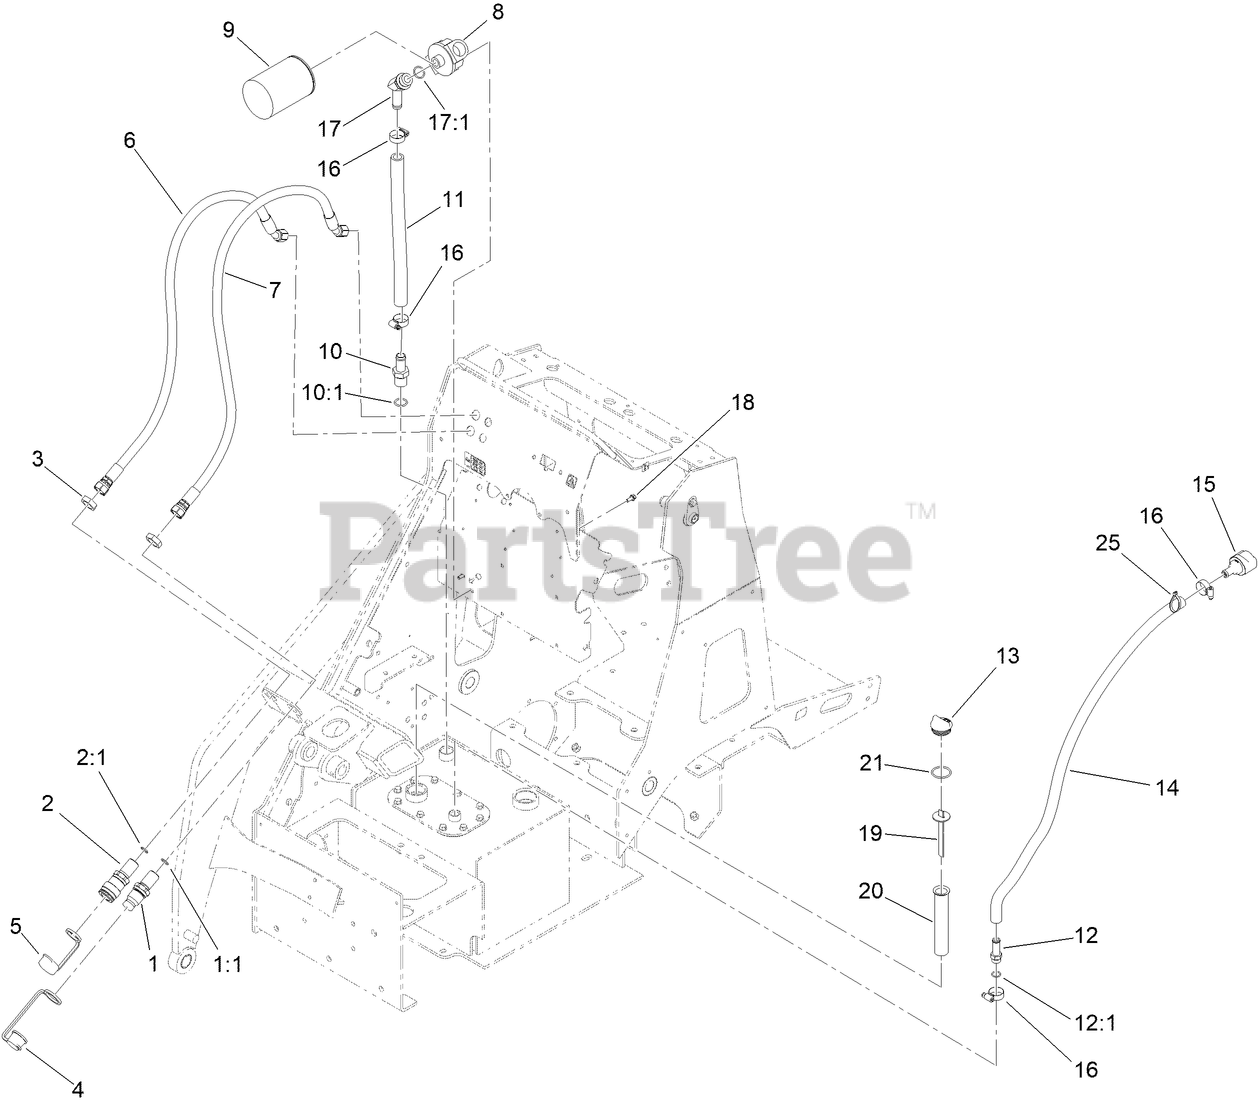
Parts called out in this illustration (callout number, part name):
1	BULKHEAD NIPPLE ASM
1:1	O-RING
2	BULKHEAD COUPLER ASM
2:1	O-RING
3	NUT-LOCK, BULKHEAD
4	CAP-DUST, NIPPLE
5	CAP-DUST, COUPLER
6	HOSE ASM-HYD
7	HOSE ASM-HYD
8	HEAD-FILTER
9	FILTER-OIL
10	FITTING
10:1	O-RING
11	HOSE-HYD, RETURN
12	FITTING-STR
12:1	O-RING
13	PLUG-PLASTIC
14	HOSE - VENT
15	BREATHER (AIR)
16	CLAMP-HOSE
17	FITTING-ELBOW45
17:1	O-RING
18	SCREW-HHF
19	DIPSTICK - OIL,
20	FILTER-SCREEN
21	O-RING
25	TIE-CABLE
